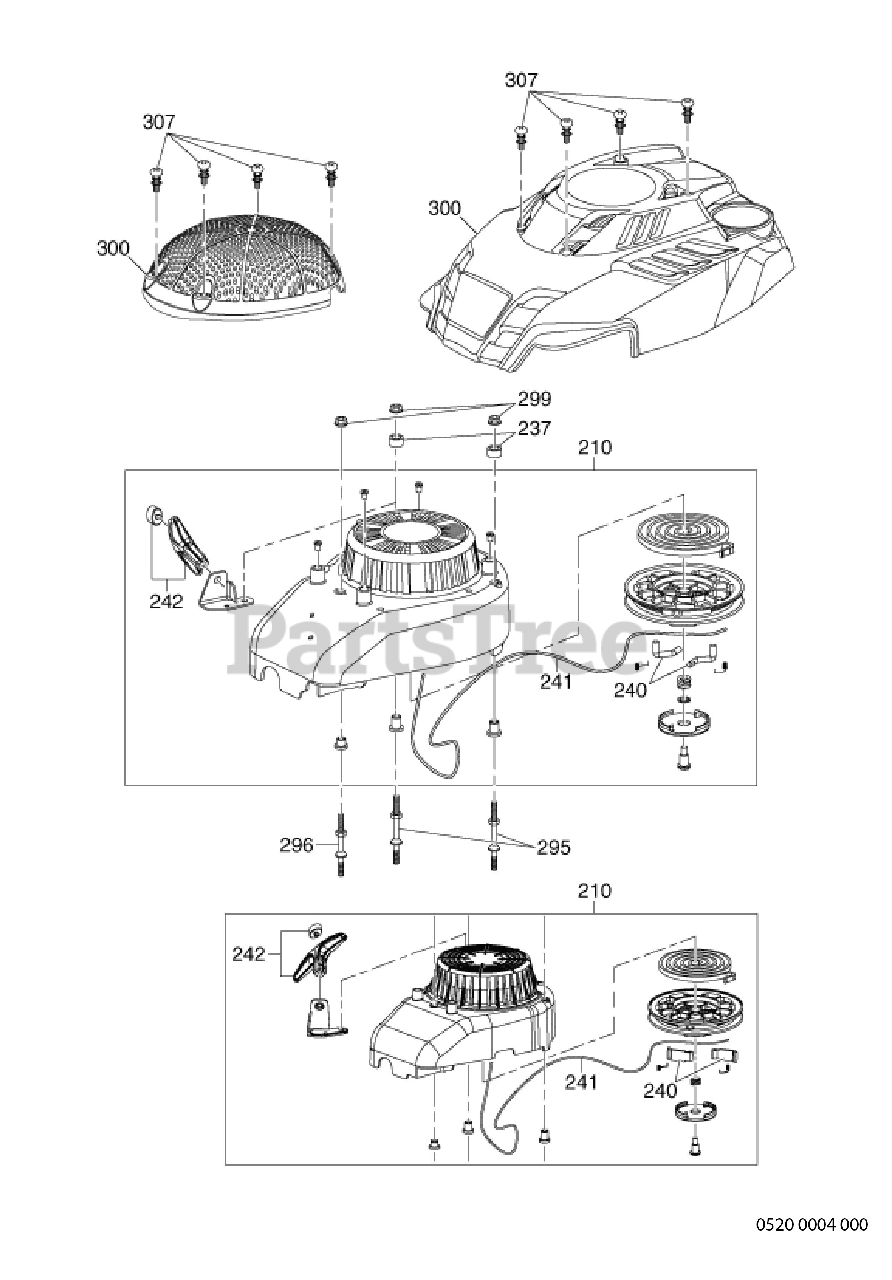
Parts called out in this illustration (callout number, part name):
210	RECOIL STARTER
241	RECOIL ROPE (2.1M)
295	STUD
296	STUD
300	ENGINE SHROUD CAP
307	SCREW ASSY M5X20
